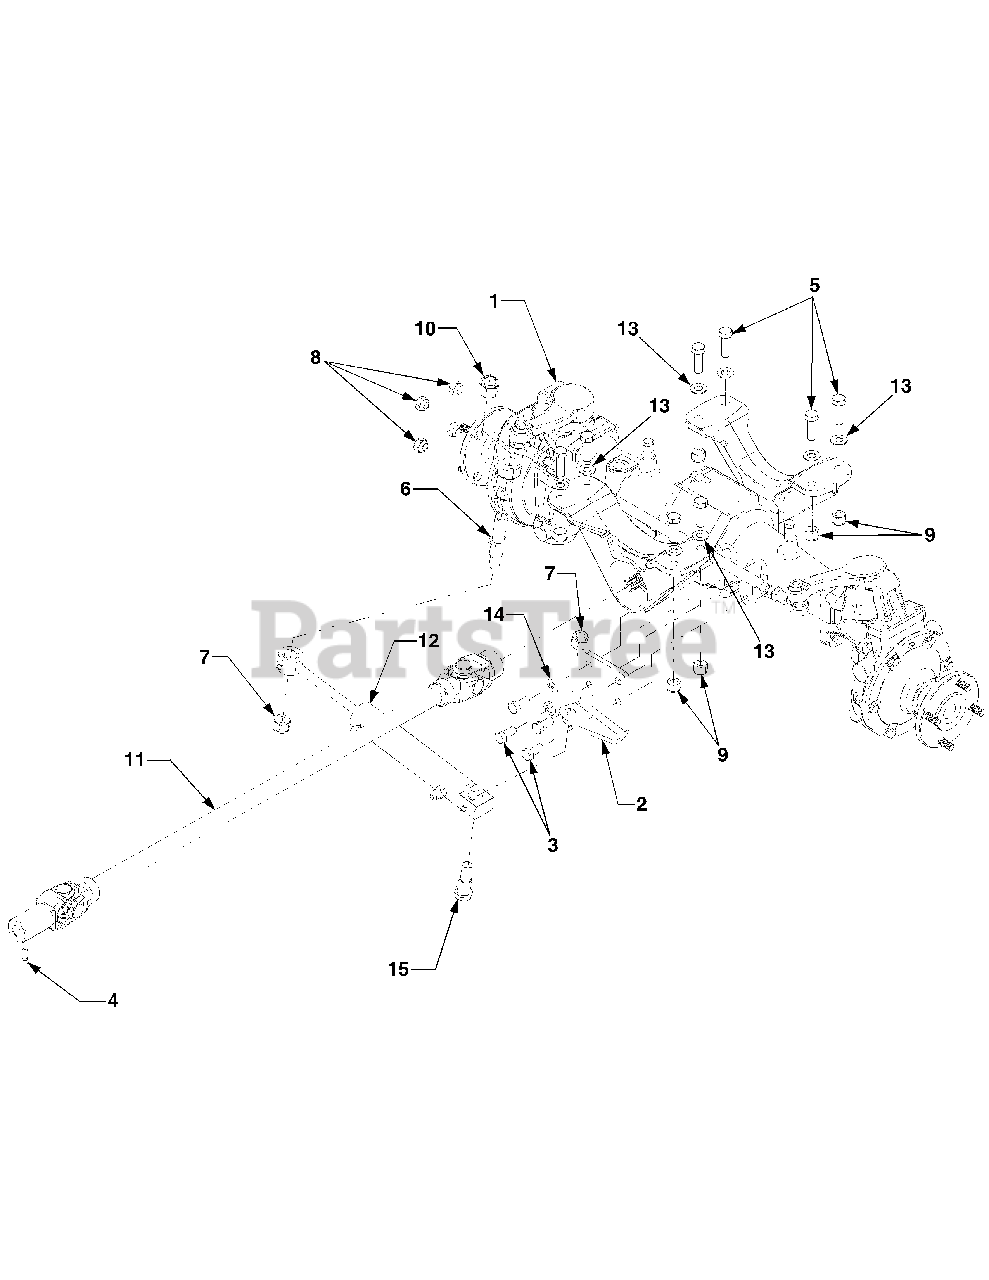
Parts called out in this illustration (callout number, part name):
1	Axle, 4WD Front
4	Screw, Sq. Hd Lock. 5/16-18
5	Screw, Hex Cap 1/2-13 x 1.5 GR5
6	Stud, Cylinder Mounting
7	Nut, Hex Insert Lock 5/8-11 GR5
8	Nut, Lug, 7/16-14
9	Nut, Hex Insert Lock, 1/2-13 GR8
10	Nut, Hex Lock, 3/4-10 GRC
11	Shaft, 4WD Drive
12	Cylinder, Steering
13	Washer, Flat, .51 x 1.0 x .06
14	Washer, Lock, 1/2
15	Screw, Shoulder, .75 x 1.03
